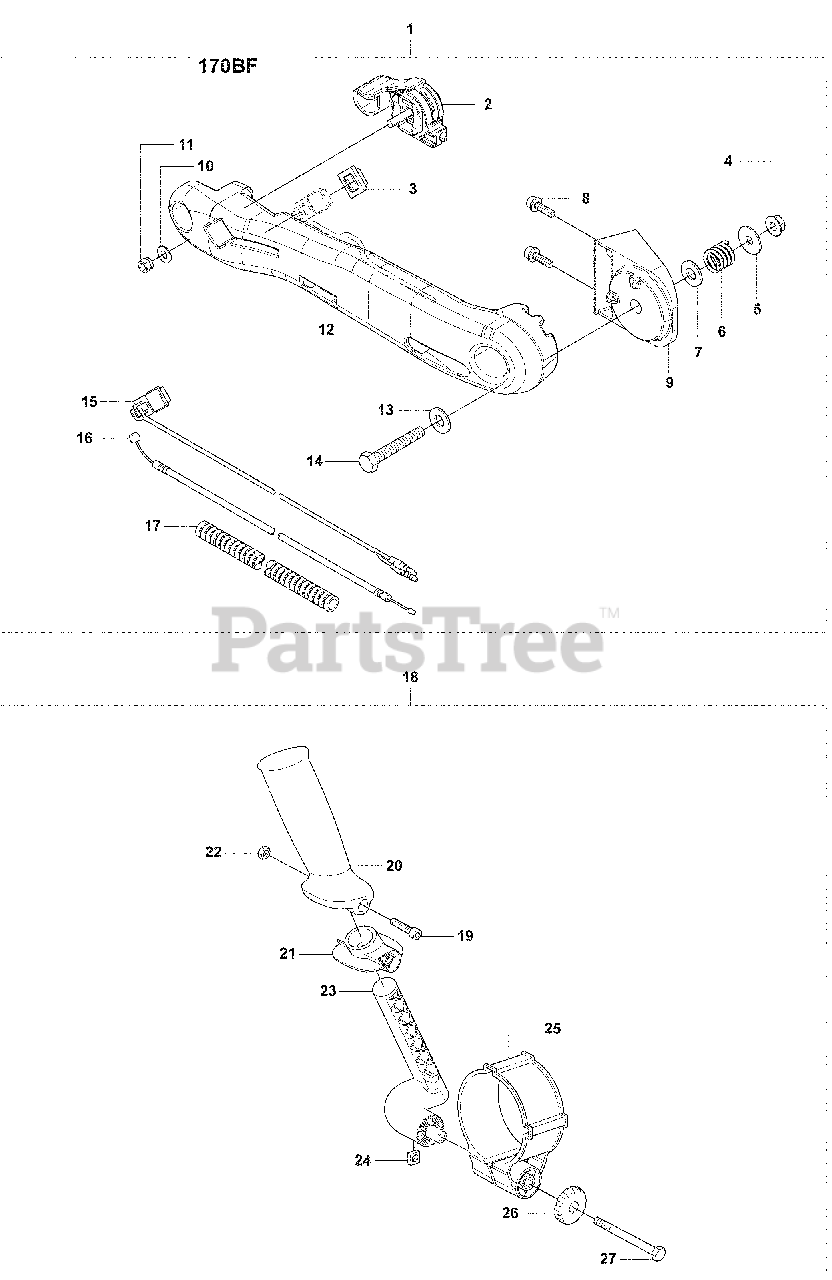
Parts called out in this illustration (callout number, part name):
1	Handle Assembly
2	Lever
3	Switch Cap
4	Nut
5	Washer
6	Spring
7	Washer
8	Screw
9	Bracket
11	Nut
12	ARM
13	Washer
14	Bolt
16	Cable, Complete
19	Screw
22	Hex Nut, M5 X .80 DIN
23	Holder
24	Square Nut
25	HOLDER TH
26	Air Filter Cover Knob
